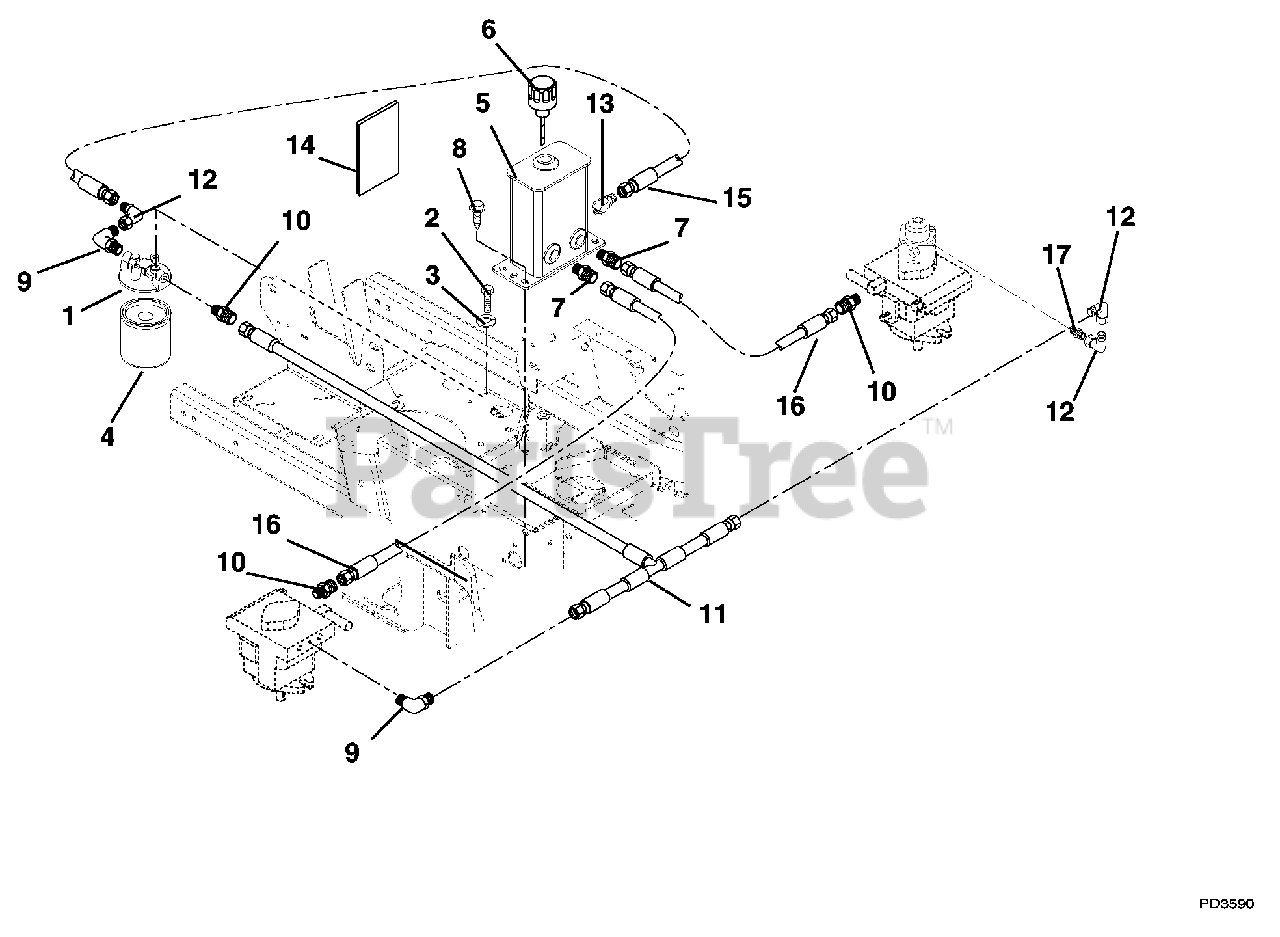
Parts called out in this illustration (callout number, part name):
1	Head, Filter
2	Bolt, Hex .25-20 x .50 Grade 5
3	Washer, Locking .25 x .062
4	Oil Filter
5	Tank, Hydraulic
6	Hydraulic Tank Dipstick
7	Adapter, Straight
8	Screw, Tapping .38-16 x .50 Hex Washer Head
9	Adapter
10	Adapter, Pipe .56-18 "O"Ring to .56-18
11	Hose, Tee Assembly .38"
13	Fitting, Hydraulic 45 Degree
14	Shield, Heat 5.50 x 4.50
15	Hose,Hydraulic
16	Hose, Hydraulic
